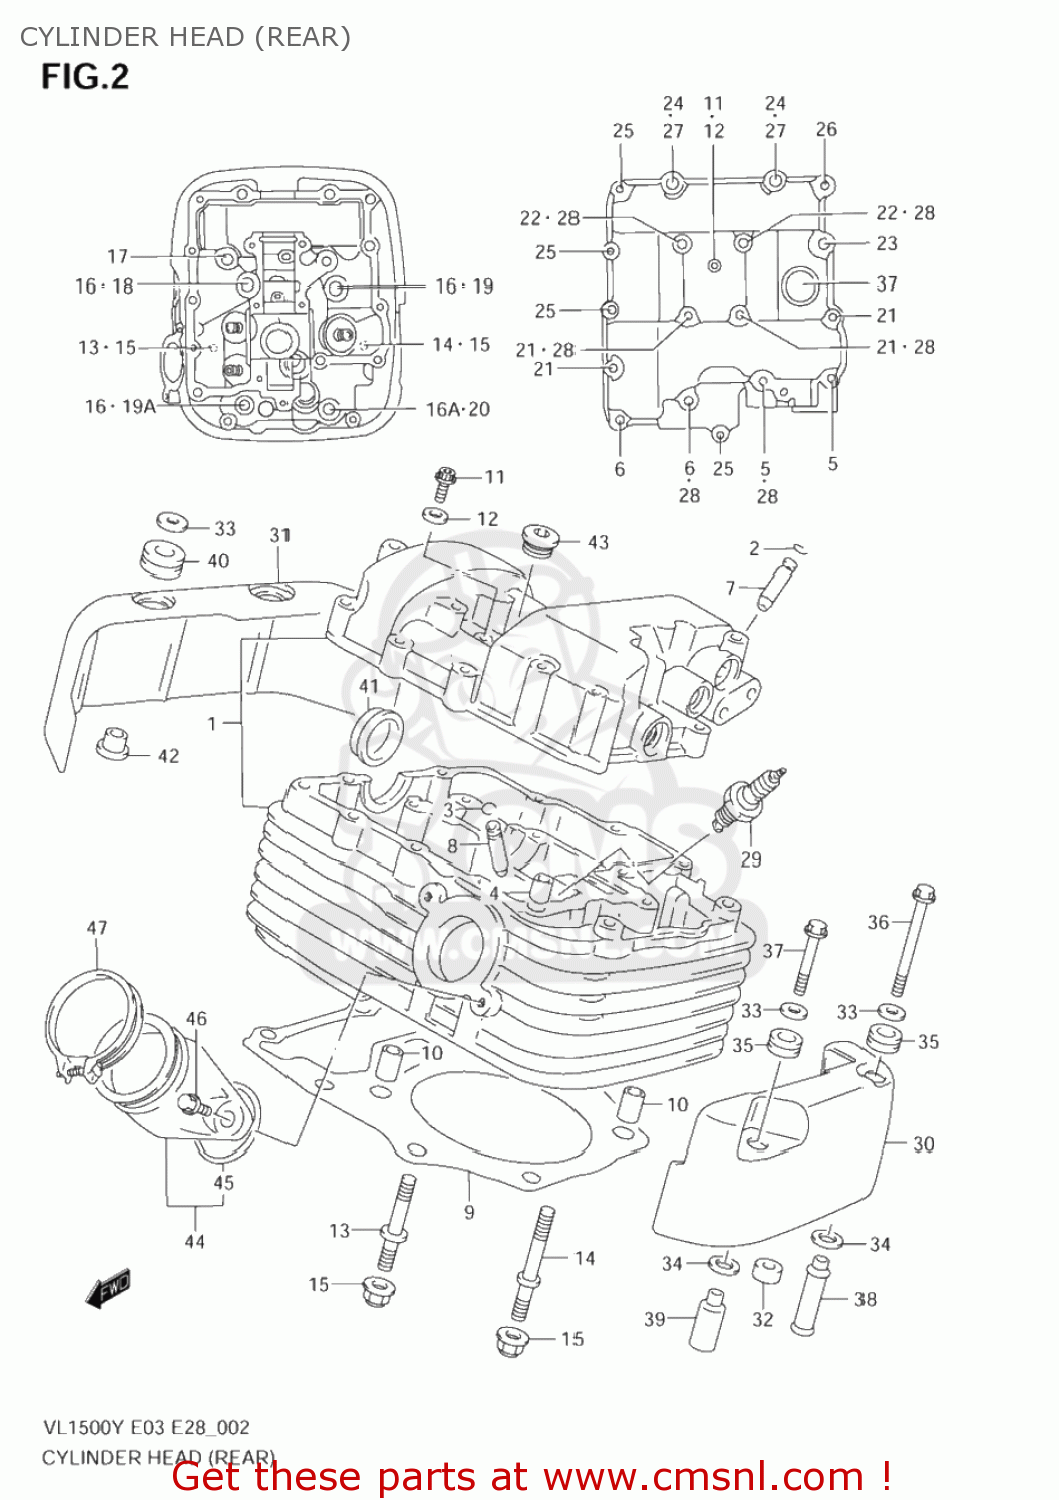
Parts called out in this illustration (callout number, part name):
1	HEAD ASSY,CYLINDER RR
2	RING,SNAP
3	RING,SNAP
4	PIN(6.2X8X11)
5	BOLT(6X60)
6	BOLT(6X55)
7	GUIDE,INTAKE VALVE
8	GUIDE,INTAKE VALVE
9	GASKET,CYLINDER HEAD RR (NAS)
10	PIN
11	BOLT
12	GASKET(6.2X13X1.2) (NAS)
13	BOLT,STUD
14	BOLT,STUD
15	NUT
16	WASHER(10.5X22X2.3)
16A	GASKET(10.5X22X2) (NAS)
17	BOLT(8X57)
18	BOLT(10X180)
19	BOLT(10X190)
19A	BOLT(10X200)
20	BOLT(10X215)
21	BOLT(6X50)
22	BOLT(6X45)
23	BOLT(8X130)
24	BOLT(8X268)
25	BOLT
26	BOLT
27	WASHER(8.5X24X1.6)
28	GASKET(5.8X13X1.2) (NAS)
29	SPARK PLUG X22E
30	CAP,CYLINDER HEAD COVER RR,L
31	CAP,CYLINDER HEAD COVER RR,R
32	CUSHION,R CAP
33	WASHER(6.5X18X1.6)
34	WASHER(9.5X20X1)
35	CUSHION
36	BOLT
37	BOLT
38	SPACER,CYL HEAD COVER CAP NO.1
39	SPACER,CYL HEAD COVER CAP NO.2
40	CUSHION
41	PLUG(OD:30)
42	BUSH
43	PLUG,22X11
44	PIPE ASSY,INTAKE RR
45	O RING(D:1.9,ID:40.7)
46	BOLT(6X16)
47	CLAMP
